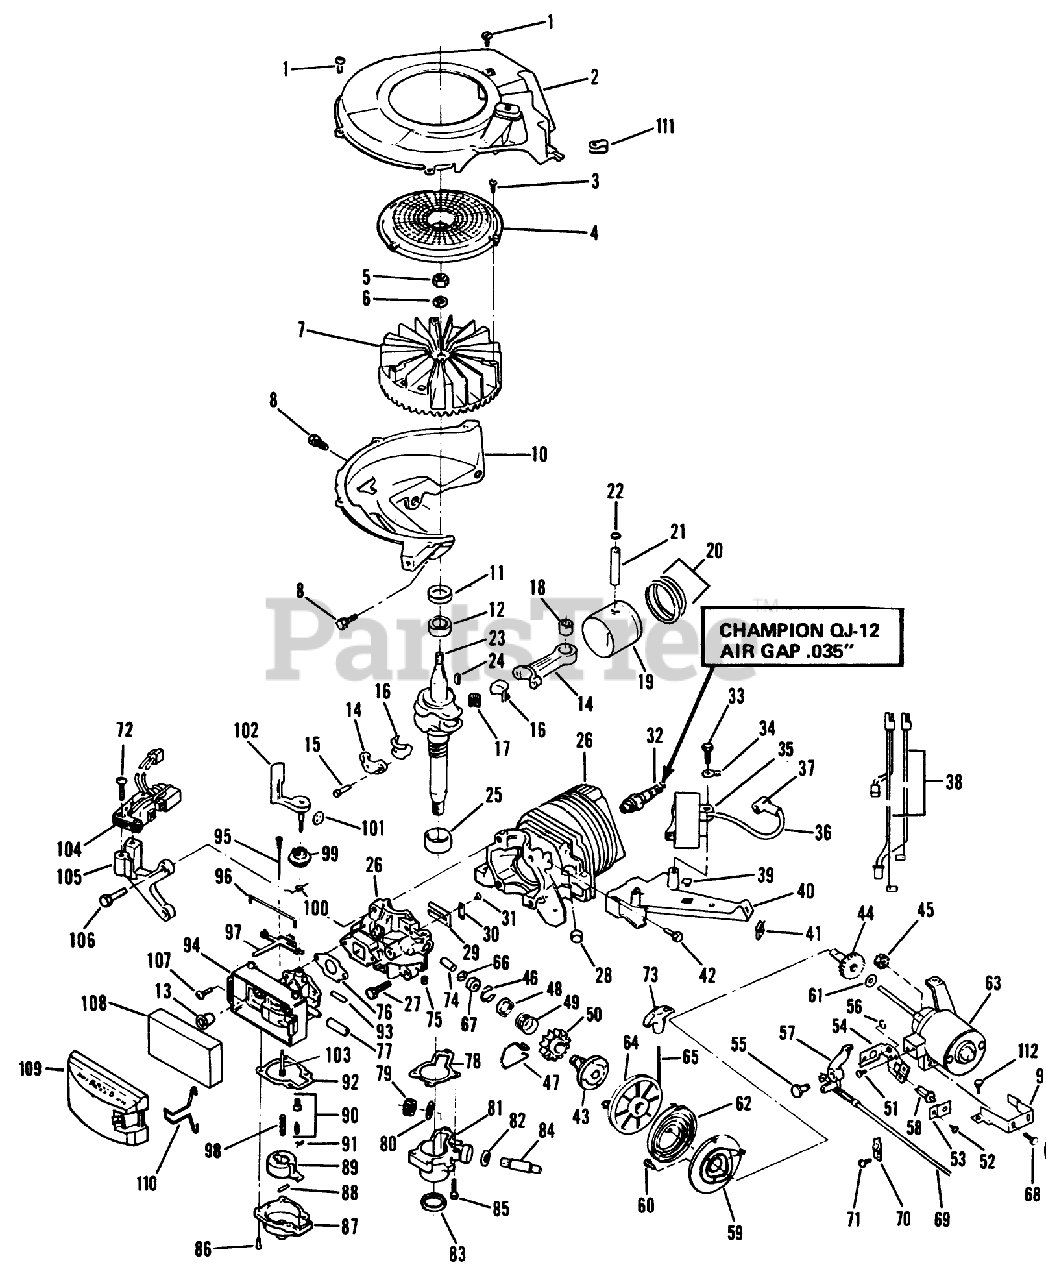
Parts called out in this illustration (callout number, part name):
1	SCREW S
2	AIR BAF&EYELET S
3	SCREW F
5	NUT
8	SCREW-SEMS
12	BEARING V
15	SCREW-HSH
16	LINER ASM
18	BEARING AY F
22	RING-RETAINING
24	KEY
25	BEARING S
27	SCREW S
28	PLUG-CORE VF
30	PLATE-BACKUP, REED
34	TERMINAL S
36	HT LEAD&COVER XEV
39	NUT-CLIP
41	NUT - SPEED S
43	CLUTCH AY S
45	PINION
46	RET.RING EF
47	SPRING F
49	*SPRING PINION EF
50	PINION EF
51	SCREW
55	PIN INTERLOCK
60	SCREW EF
62	SPRING S
64	PULLEY & CLUTCH BEARING
68	SCREW
70	CLIP S
73	HANDLE STARTER S
74	SLEEVE F
76	GASKET CARB S
78	GASKET S
79	GEAR, DR SHAFT S
80	THRUST WASHER
82	SEAL S
83	SEAL-OIL
86	SCREW-HH
93	TUBING PRIMER S
94	CARB BODY S
95	NEEDLE ADJ. AY S
96	RETAINER
97	LEVER S
98	FILTER-FUEL VS
99	COLLAR-ADJUST, AIRVANE
100	SPRING,THROTTLE S
101	DISC S
102	AIR VANE&SHAFT S
107	SCREW
110	RETAINER-COVER, FILTER
